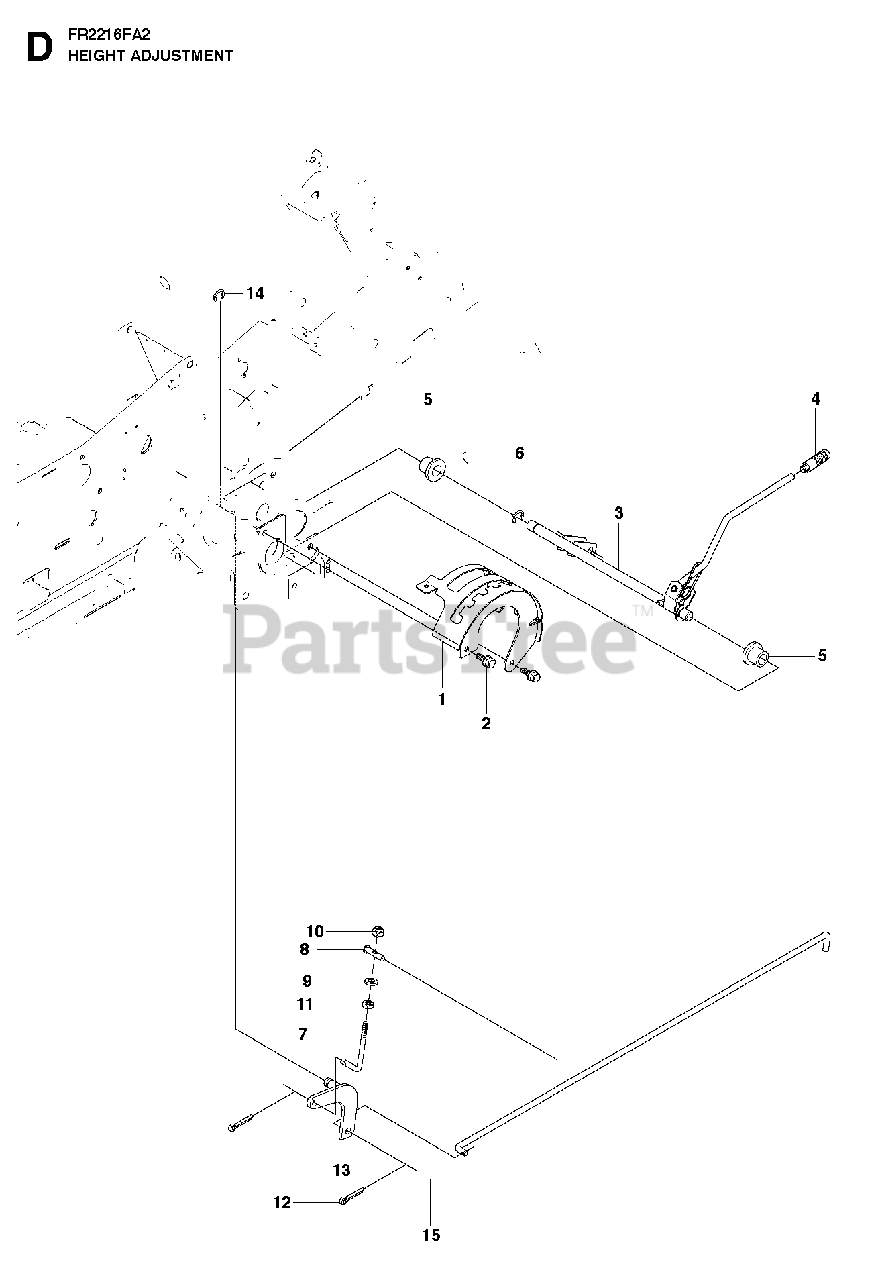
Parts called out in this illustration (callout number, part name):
1	CONTROL PLATE
4	GEAR STICK KNOB
5	BUSHING
9	WASHER
10	LOCKNUT M8
11	NUT
12	SPLIT PIN
14	RETAINING RING
15	CONNECTION ROD
